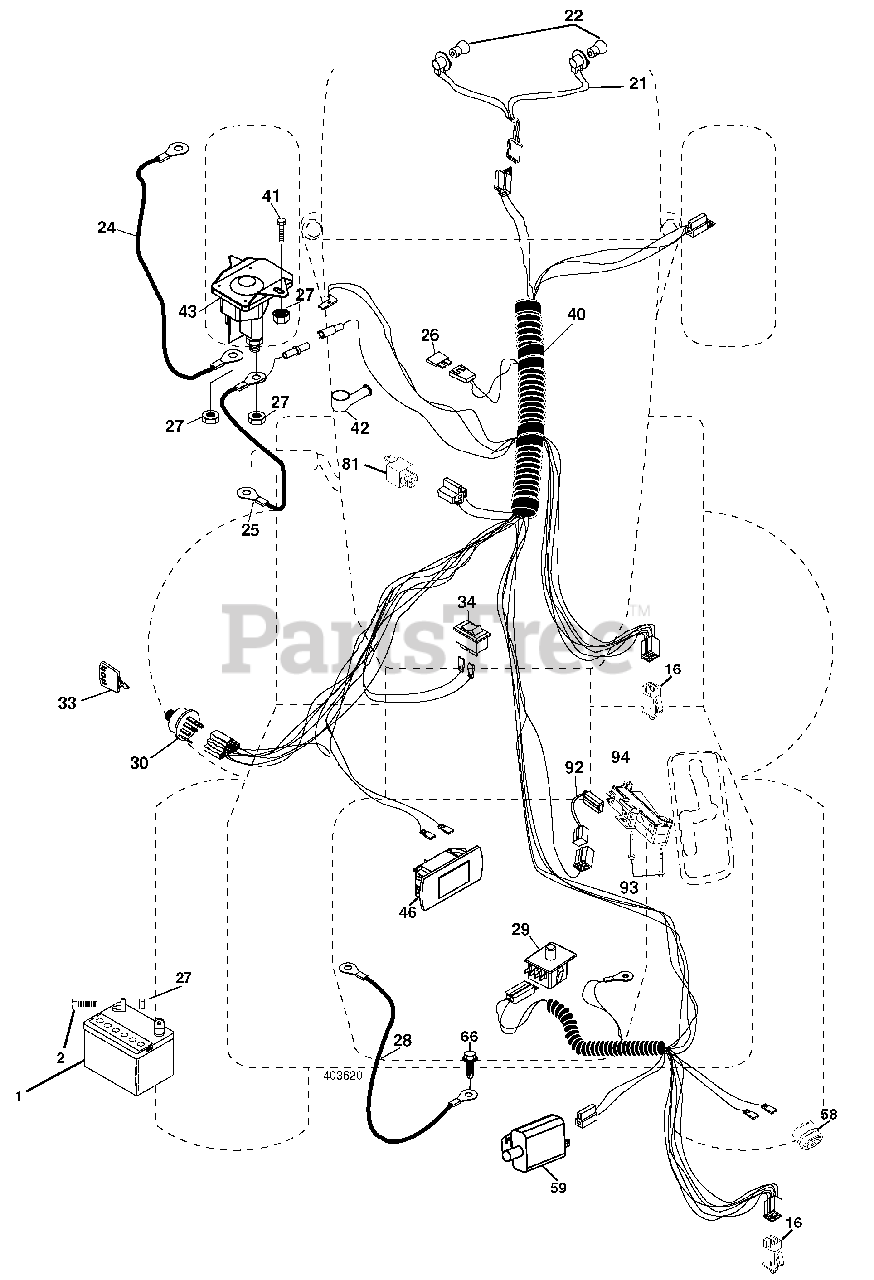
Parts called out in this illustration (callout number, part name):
1	Battery
2	Bolt Hex Hd 1/4-20 unc x 3/4
16	Switch Interlock
21	Harness Asm Light W/4152J
22	Bulb Light #1156
24	Cable Starter 6 Ga. 11" Red
25	Cable Battery Crd 56" Red
27	Nut Keps Hex 1/4-20 unc
28	Cable Ground 6 Ga. 18" Black
30	Switch Ignition
34	Switch Light/Reset B/B/Red
40	Harness Ignition
41	Bolt Flk Fin Hex 1/4-20 unc x 1/2
42	Cover Terminal Red
43	Solenoid
46	Gauge Service Reminder/Hrmtr Rect
58	Buzzer Crd
59	Switch FBI CRD
66	Screw Thdrol 3/8-16 x 1/2 Ty-Tt
92	Harness Pigtail Console ROS
93	Screw Plastite 10-14 x 2.0
94	Module Reverse ROS
